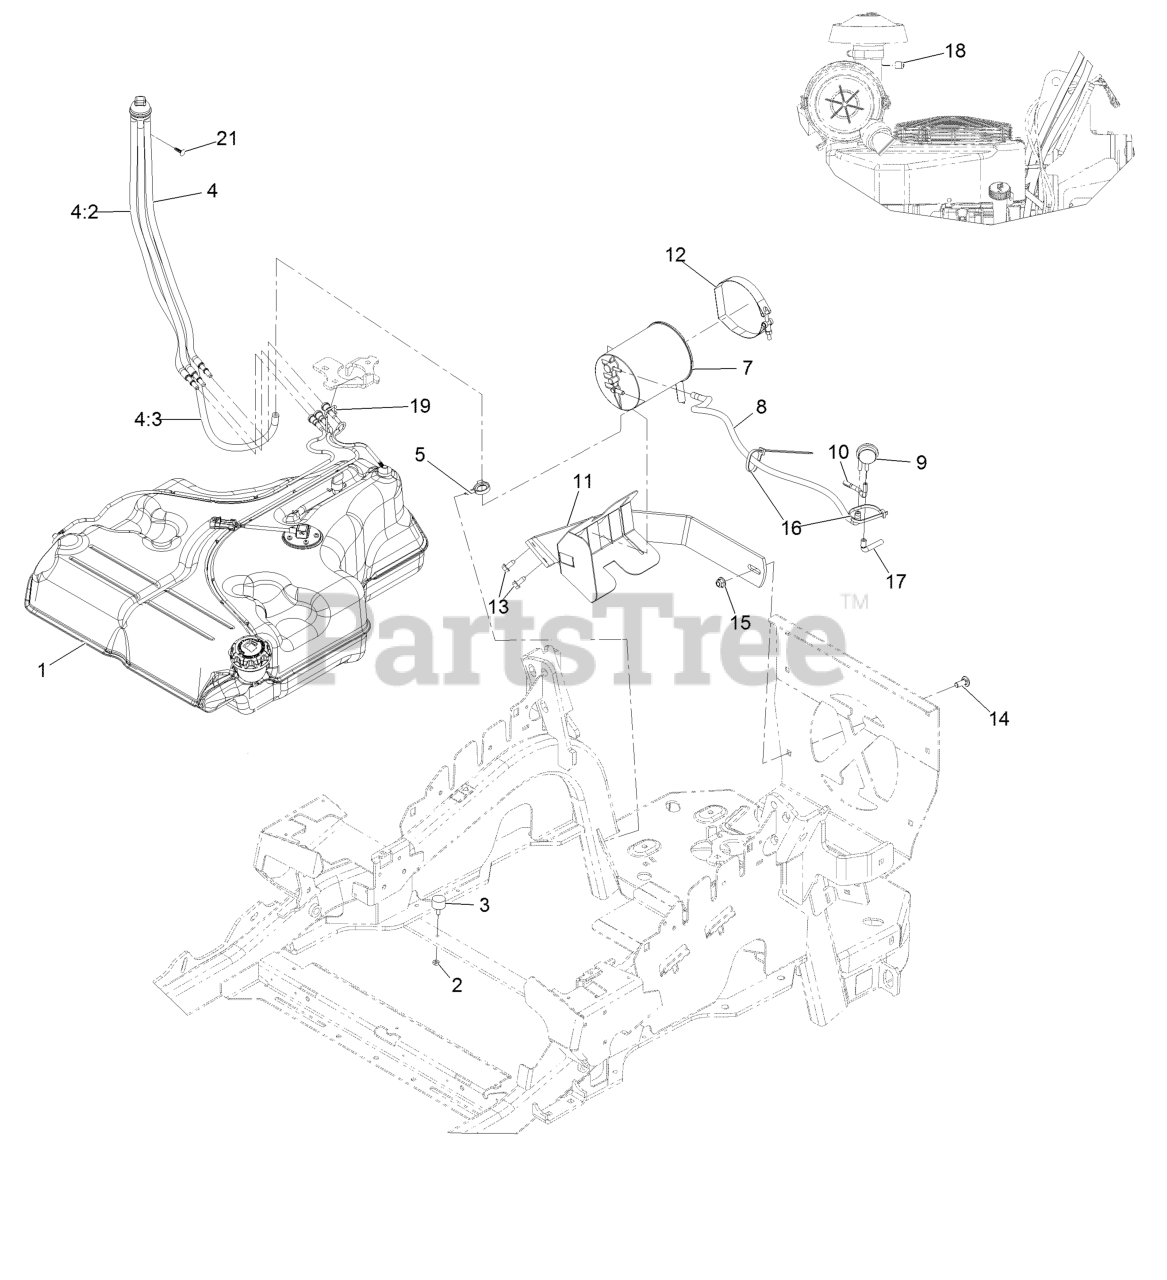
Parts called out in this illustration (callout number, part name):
1	Fuel Tank ASM
2	Nut-Jam 1/4-20
4	Fuel Manifold Vent ASM
4:2	Hose-Fuel Line 24"
4:3	Hose-Fuel
5	Clamp-Hose
7	Canister-Carbon, 1200Cc
8	Hose-Vent, Formed
9	Valve-Control, Vacuum
10	Hose-Vent, Formed
11	Mount-Canister
12	Clamp, T-Bolt
13	Screw-HWH 5/16-18 X 3/4 Tf
14	Bolt-Carriage 3/8-16 X 1
15	Nut-Nyloc 3/8-16 Flg
16	Tie-Cable 7 15/16 (Large)
17	Hose-Vent, Formed
18	Plug-Port
19	Retainer-Line, Vapor
21	Plug-Plastic
